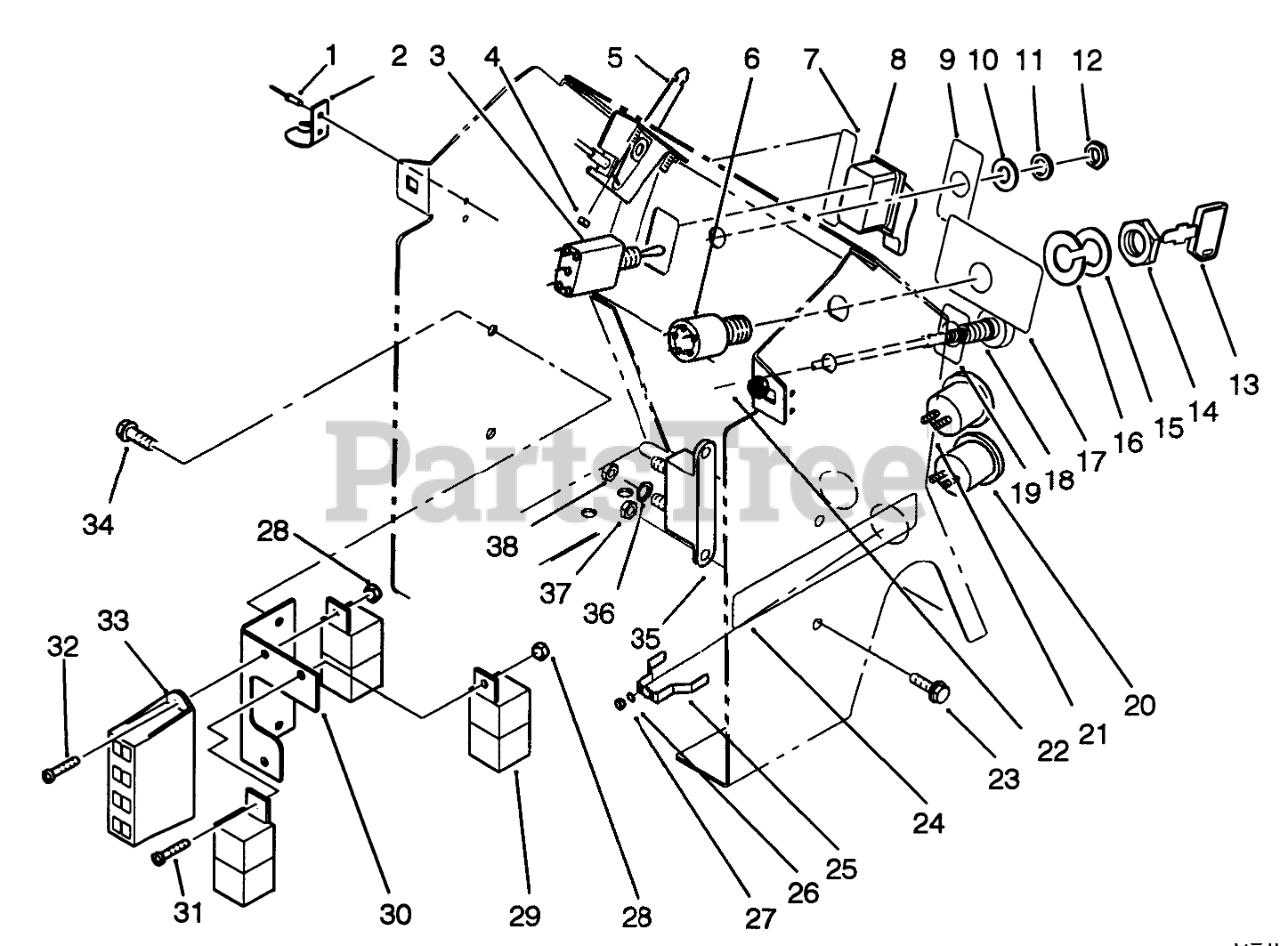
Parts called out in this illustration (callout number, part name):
1	POPRIVET 1/8X 1/8 BK
2	KEEPER-LATCH
3	Switch-Lights (Incl. Ref. #10-12)
4	Nut
5	CONTROL-THROTTLE
6	Switch-Ignition, Assembly (Incl. Ref #13-16)
7	DECAL-PTO
8	PTO-SWITCH W/COVER
9	DECAL-LIGHTS
10	TAB-WASHER
11	Washer
13	Key
15	Washer
16	LOCKWASHER
17	DECAL-IGNITION
18	CONTROL-CHOKE
19	DECAL-CHOKE
20	Meter-Hour (Incl. Ref. #20 & 23-25)
21	VOLTMETER
22	NUT-HJ
23	SCREW-HHF
24	DECAL-MODEL HYDRO
25	CLAMP-HOUR METER
26	WASHER-LOCK
28	Nut
29	RELAY
30	BRKT-FUSE HOLDER B
31	SCREW-PPH
32	SCREW
33	FUSE-HOLDER 4 WAY
34	TRS-1/4-20X1/2 BLACK
35	Solenoid
36	WASHER-LOCK
37	NUT-HEX
38	NUT-JAM
